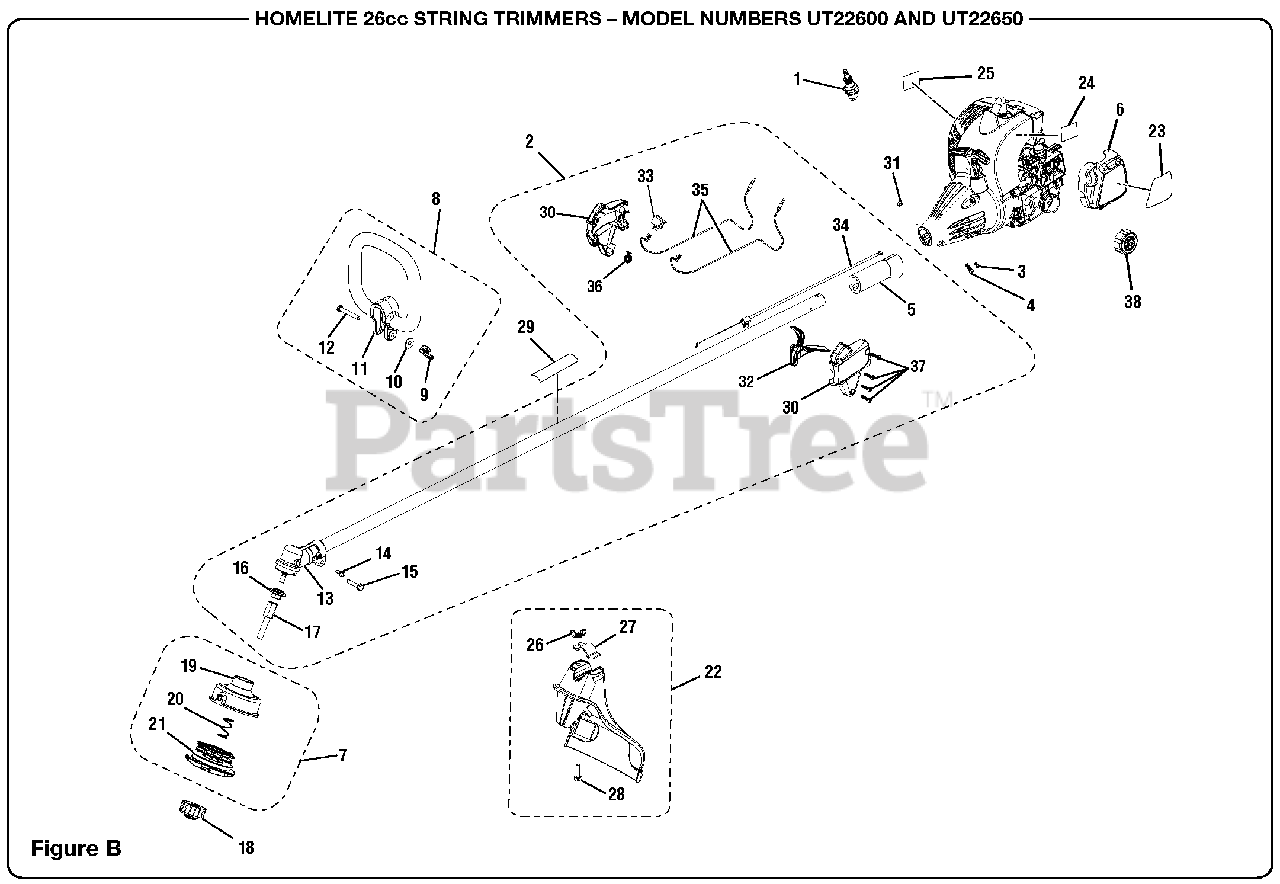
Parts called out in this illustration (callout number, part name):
1	Spark Plug (Champion RCJ6Y)
2	Boom Assembly
3	Screw (8-16 x 5/16 in.)
4	Screw (M6 x 20 mm)
5	Rubber Grip
6	Air Box Cover
7	String Head Assembly
8	Front Handle Assembly
9	Wing Nut (1/4-20)
11	Front Handle
12	Bolt (1/4-20 x 2 in.)
13	Gear Head
14	Screw (10-25 x 5/16 in.)
15	Screw (1/4-20 x 1.25 in.)
16	Flange Washer
17	Adaptor
18	Spool Retainer
19	String Head Housing
20	Spring
21	Spool
22	Grass Deflector Assembly (Incl. Key Nos. 26-28)
23	Starting Label
24	Model Label
25	Combustion Warning Label
26	Wing Nut (1/4-20)
28	Bolt (Square Head)
29	Icon Strip
30	Handle Assembly
31	Hex Nut (M6)
32	Throttle Trigger
33	Switch
34	Throttle Cable
35	Electrical Lead
36	Trigger Spring
37	Screw (M4 x 20 mm)
